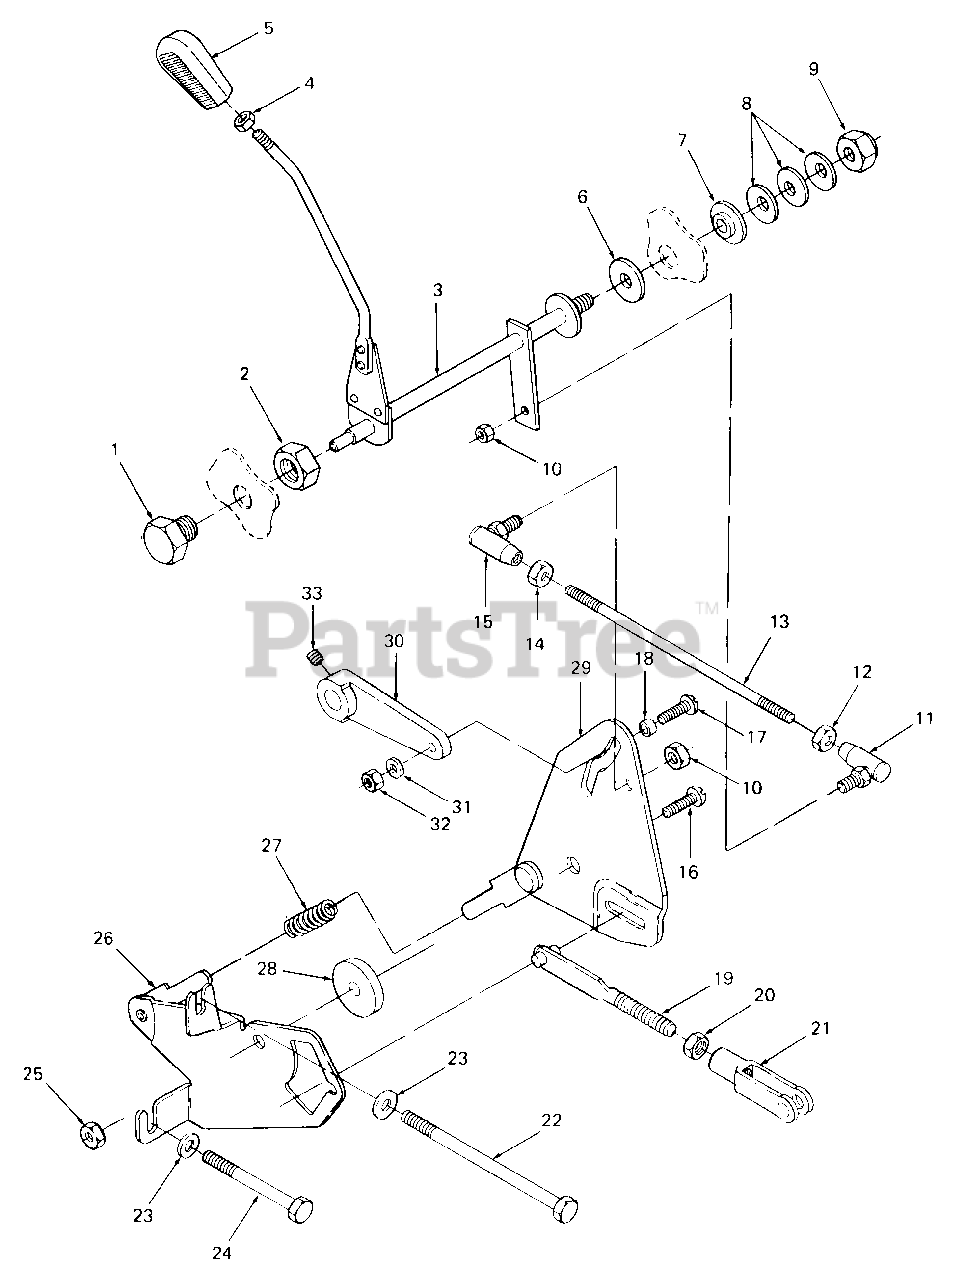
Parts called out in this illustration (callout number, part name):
1	Screw, Rockshaft Bearing, 3/4-16 X .75 Lg
2	Nut, Hex Jam, 3/4-16 GR5
3	Shaft Assy, Cross
4	Nut, Hex Jam, 3/8-16 GR5
5	Knob, Speed Control
6	Disc, Friction
7	Spacer, Shouldered
8	Washer, Bell
9	Nut, Hex Top Lock, 1/2-20
10	Nut, Hex Patch Lock, 5/16-24
11	Ball Joint, 5/16-24
12	Nut, Hex Jam, 5/16-24 Trd
13	Rod, Connecting
14	Nut, Hex Jam, 5/16-24 LH Trd
15	Ball Joint, 5/16-24 LH Trd
16	Screw, Truss Hd, 5/16-18 X 1
17	Screw, Truss Hd, 1/4-20 X 1
18	Spacer, 3/8 OD X .700
19	Rod, Control
20	Nut, Hex Jam, 3/8-24 GR5
21	Clevis Adjustment
22	Bolt, Hex Patch, 5/16-18 X 5.5 Lg GR5
23	Washer, Flat, .344 X .750 X .105 Thk
24	Bolt, Hex Patch, 5/16-18 X 3.0 Lg GR5
25	Nut, Hex Jam, 5/16
26	Arm Assy, Cam
27	Spring, Compression
28	Spacer, Shouldered
29	Cam Assy, Return
30	Pintle, Control
31	Washer, Lock, 1/4
32	Nut, Hex, 1/4
33	Set Screw, Socket w/Patch
